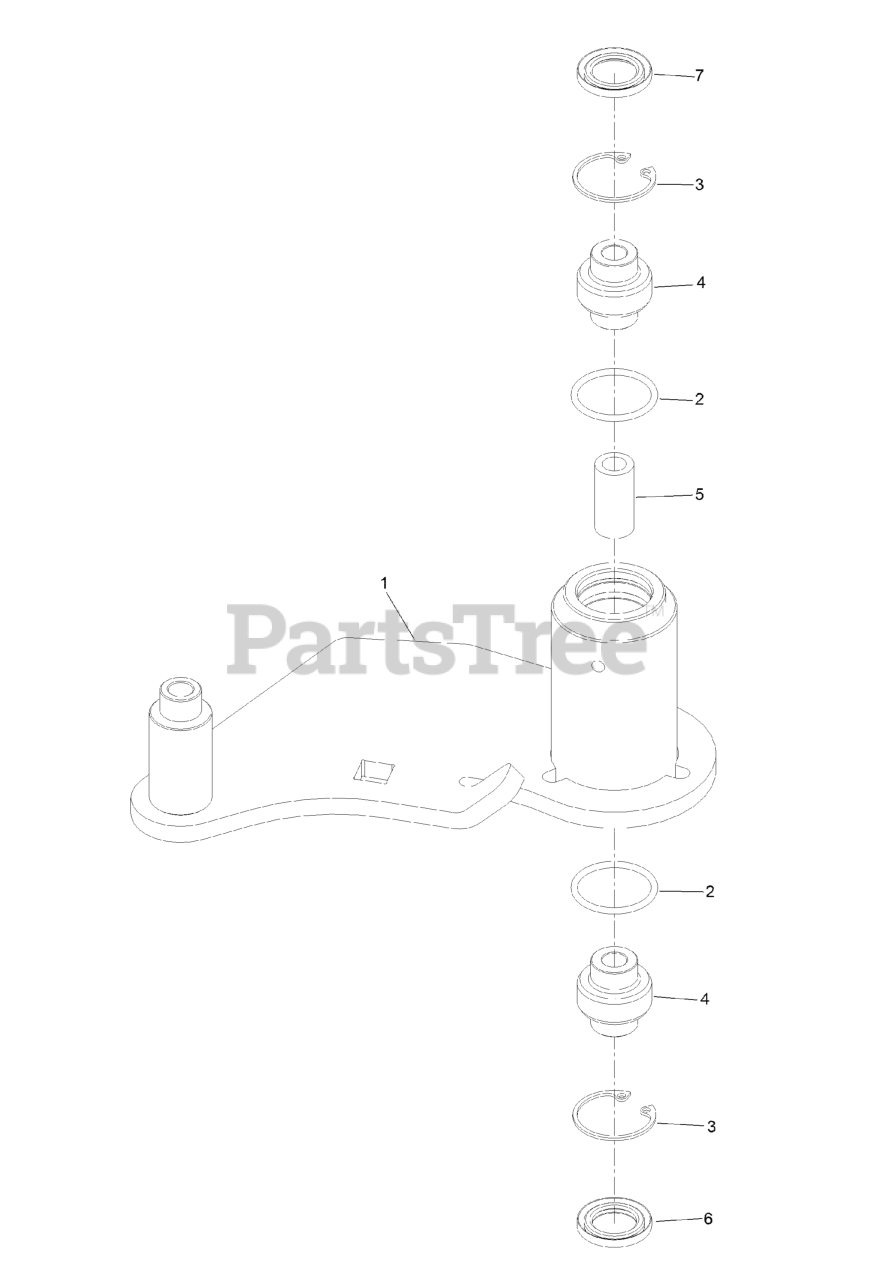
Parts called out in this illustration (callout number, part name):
1	Idler-Deck
3	RING-SNAP
4	BEARING-SPHERICAL
6	SEAL-LIP, DOUBLE
7	SEAL-LIP, SINGLE
